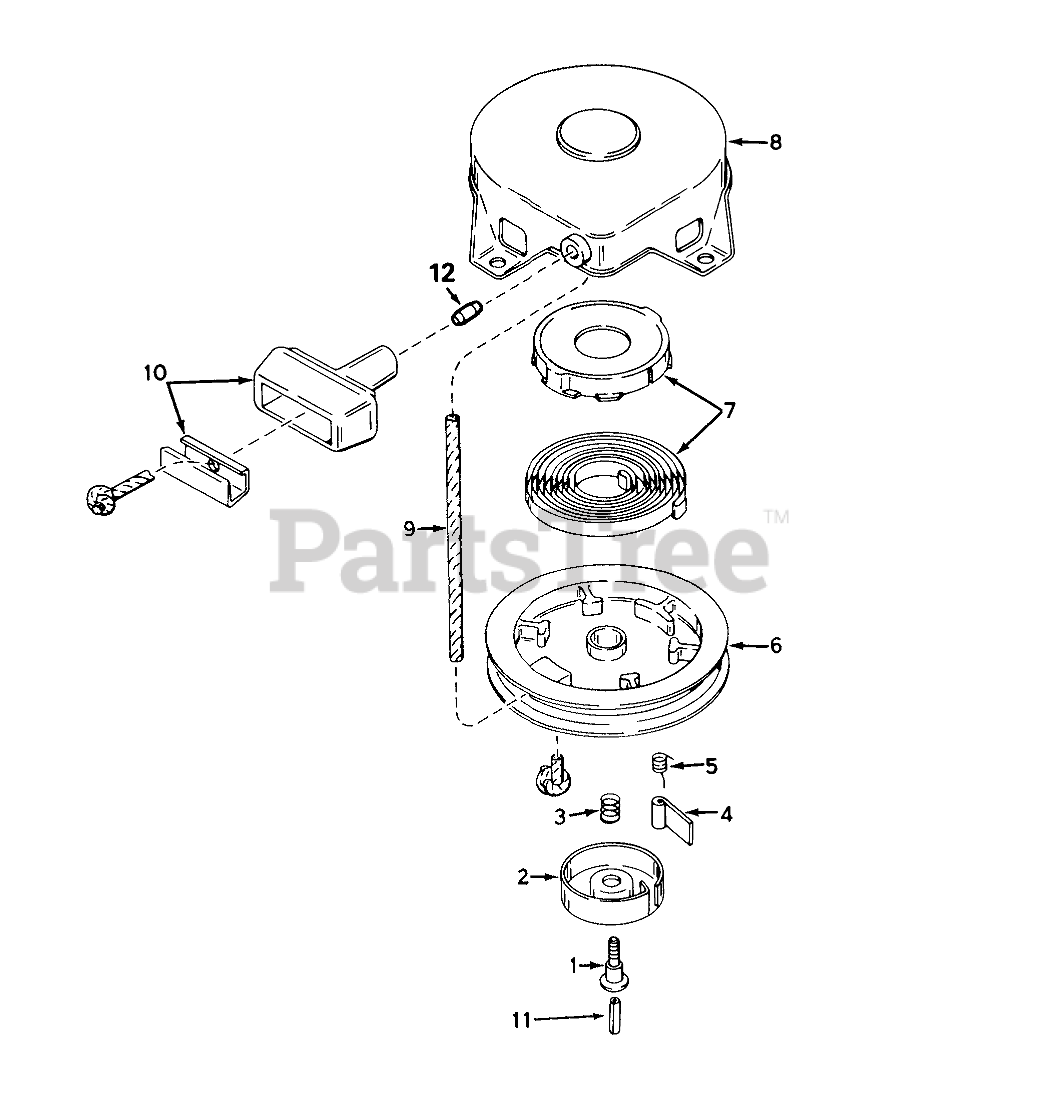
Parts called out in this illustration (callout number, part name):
2	Retainer
3	Spring-Brake
4	Dog-Starter
5	Spring-Dog
7	Spring & Keeper Assy
8	Housing Assembly-Starter (Incl. #1)
9	Rope-Starter (98 cut to length)
10	Assy., Starter
11	Centering
12	Retainer-Starter Rope
